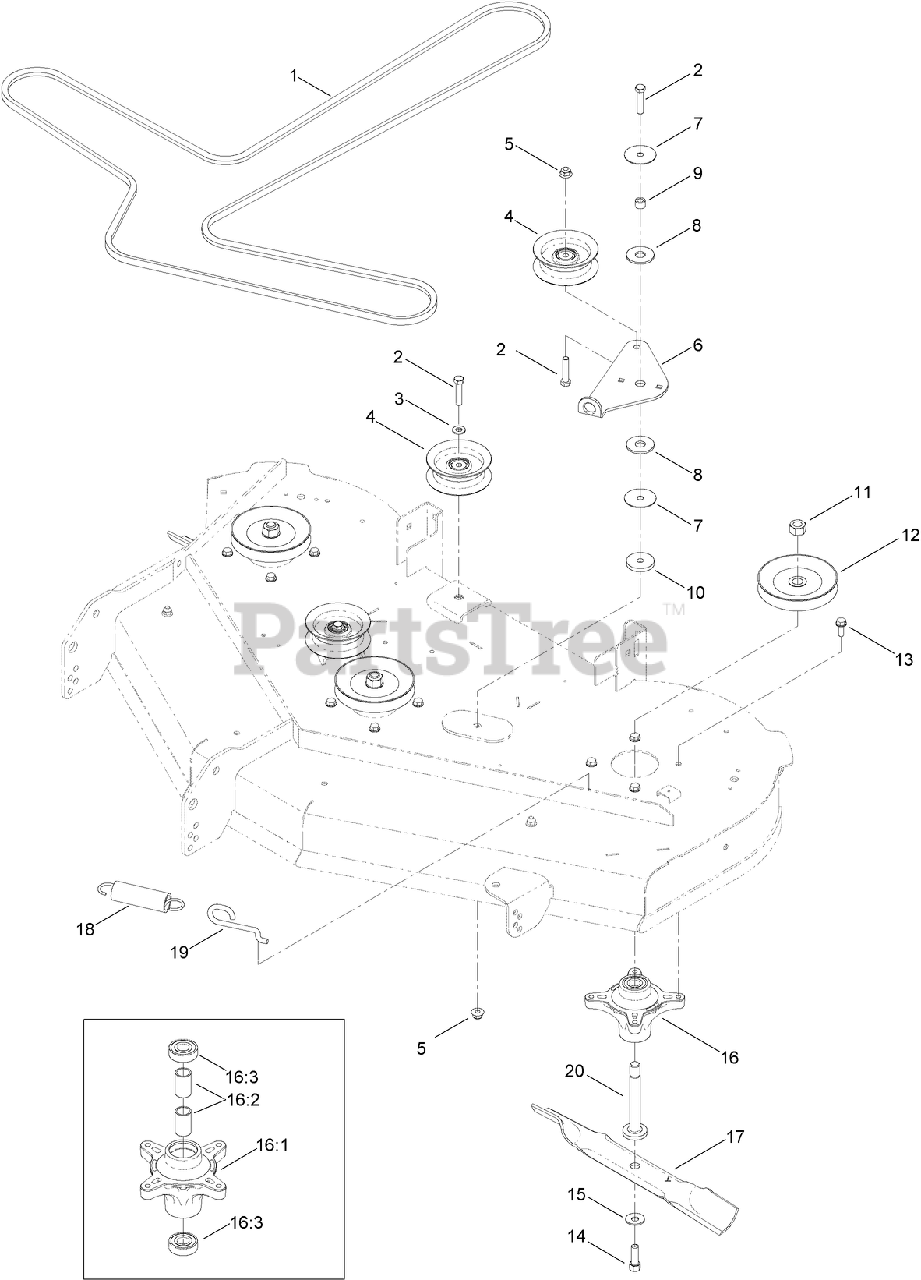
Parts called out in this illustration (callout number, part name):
1	V-BELT
2	SCREW-HH
3	WASHER-FLAT
5	NUT-HF, NI
6	ARM-IDLER
7	WASHER
8	WASHER-FRICTION, COMPOSITE
9	SPACER
10	SCREW-HH
11	NUT-HEX
12	PULLEY
13	SCREW-TAPTITE
14	SCREW-HH
15	WASHER-BELLEVILLE
16	SPINDLE ASM
16:2	SPACER
17	BLADE-HI LIFT
18	SPRING-EXTENSION
19	HOOK-RETURN, SPRING
20	SHAFT-SPINDLE
